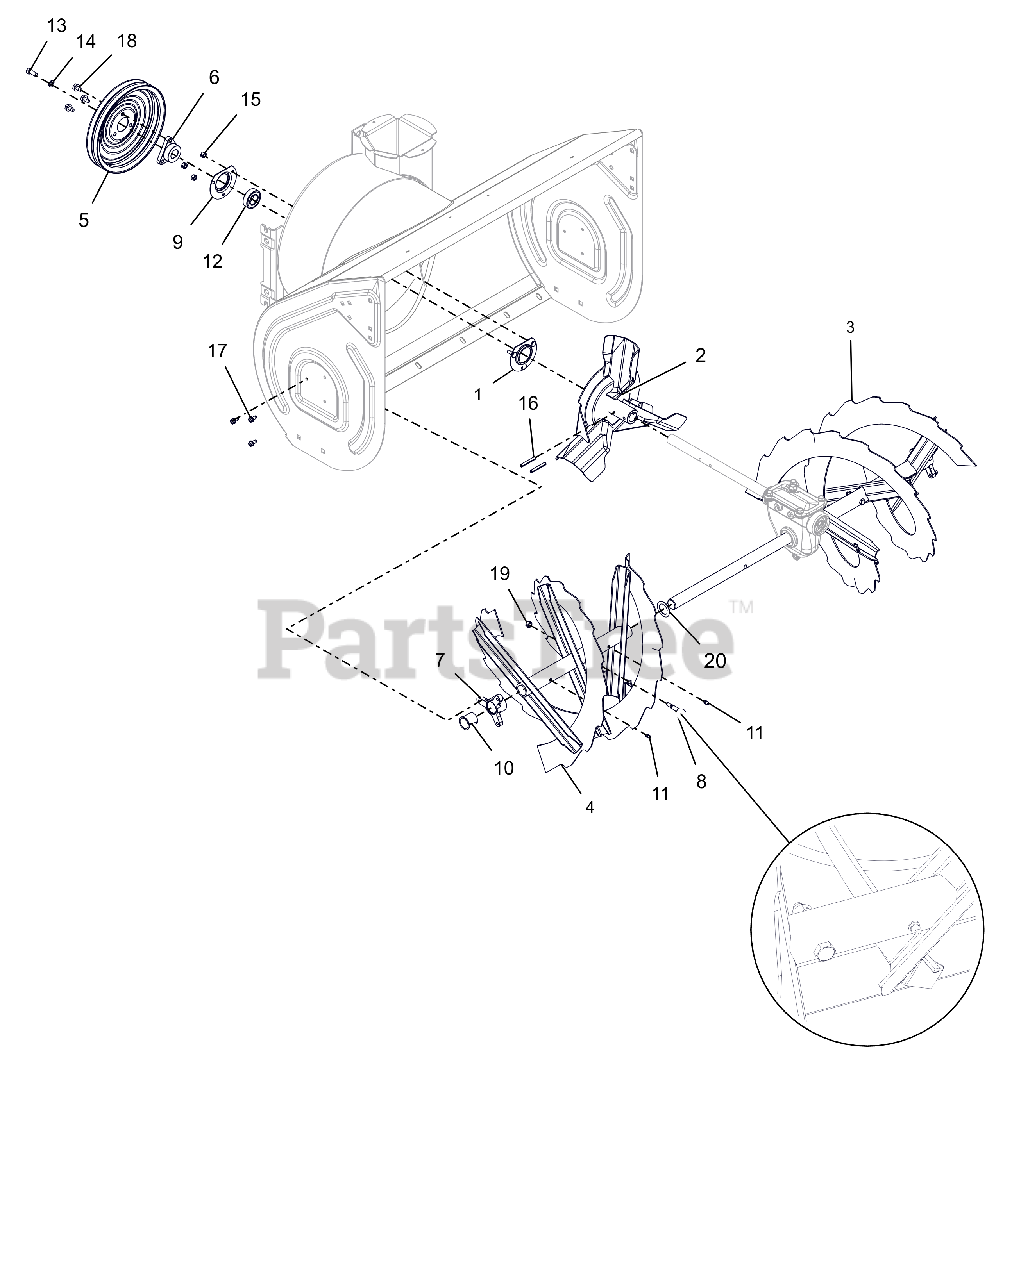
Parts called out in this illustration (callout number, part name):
1	BEARING FLANGE
2	IMPELLER, 3 BLADE-14"
3	RAKE, LH-32"(1 ID X 15.75 OD)
4	RAKE, RH-32"(1 ID X 15.75 OD)
5	PULLEY, SPIN FORM DUAL GROOVE
6	PULLEY HUB, D-BORE .87 PRO
7	BUSHING, RAKE SHAFT 1"
8	BOLT, SHEAR - DELUXE
9	BEARING FLANGE
10	BSHG-FLG SPLIT NYLINER 1.0" HP
11	ZERK,FITTING .25X.125 DRIVE IN
12	BRG-BALL .876X1.75X.50 RSTFP
13	BLT-HEX .31-24X.75 YWZC GR5
14	WSHR-LK .312X.097 HVY YWZC
15	@NUT-LK-CTR .25-20 YWZC
16	PIN-ROLL .250X1.75
17	SCR-TAP .25-20X.50 HWH TR YWZ
18	@SCR-TAP .31-18X.50 HWH TR YWZ
19	@NUT-LK-CTR .31-18 YWZC
20	WSHR-FL-STL 1.010X1.505X.062YZ
